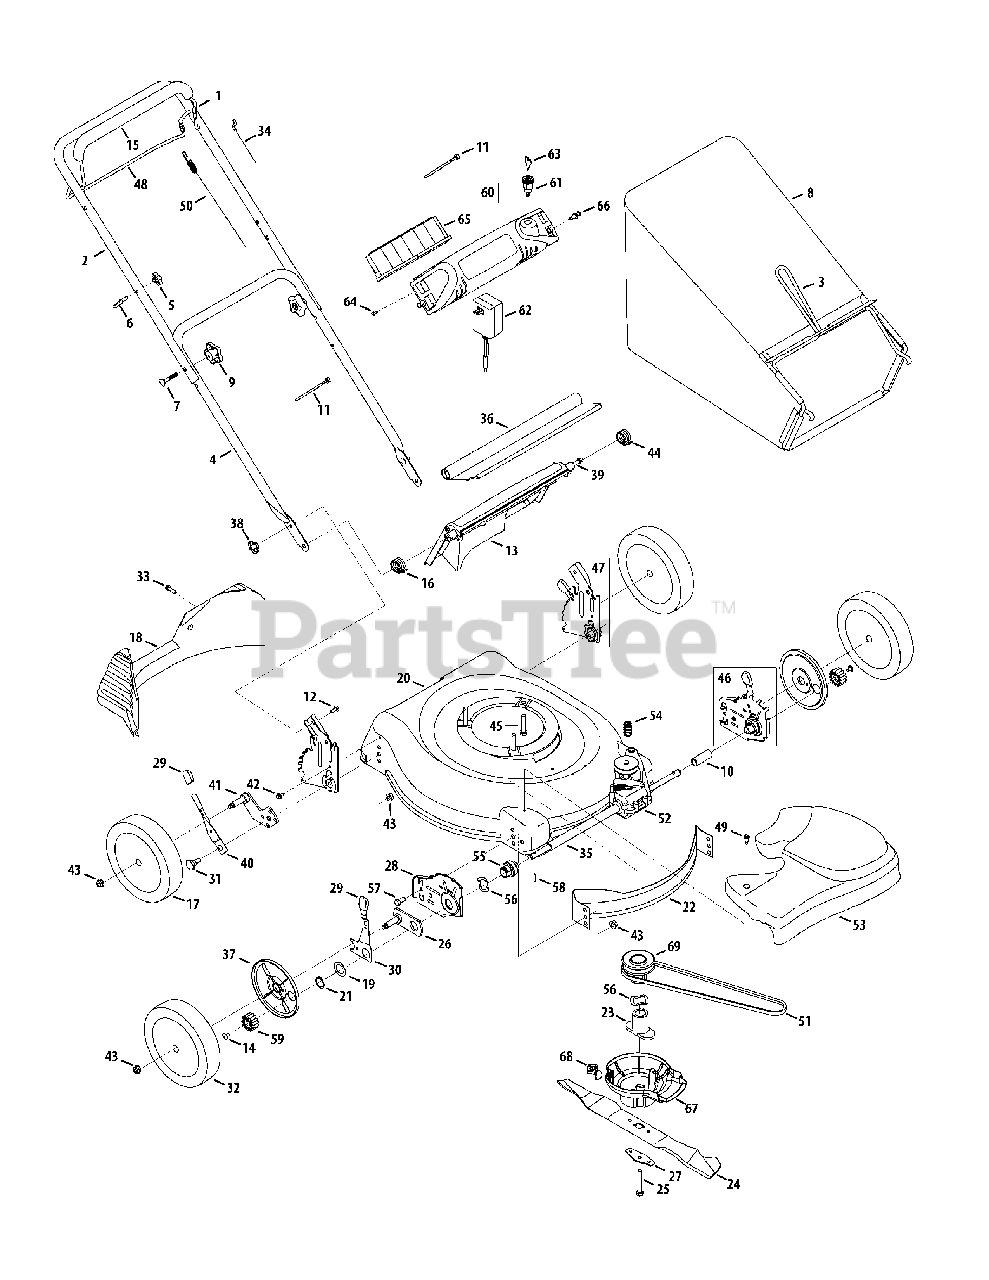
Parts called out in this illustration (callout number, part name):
6	Rope Guide
7	Carriage Bolt ,5/16-18 x 2
8	Grass Bag Assembly
9	Hand Knob
10	Sleeve Spacer - LH
11	Cable Tie
12	Carriage Bolt ,1/4-20
13	Rear Discharge Door
14	Screw 1/4-20
15	Bail Cover
16	Torsion Spring - RH
17	Rear Wheel, 8" x 2.125"
18	Rear Baffle
19	Washer, 1.5" OD
21	Snap Ring
22	Front Baffle
23	Blade Adapter
23	One Piece Blade Adapter
24	21" Mulch Blade
25	Hex Bolt , 3/8-24 x 2.5
26	Pivot Plate Assembly
27	Blade Bell Support
28	Height Adjustment Plate - RH
28	Height Adjustment Plate - LH
29	Adjustment Lever Knob
30	Front Lever - RH
30	Front Lever - LH
31	Shoulder Screw
32	Front Wheel, 8" x 2.125"
33	Screw, 1/4-15 x 1.000
34	Control Cable - 40.75"
35	Sleeve Spacer - RH
36	Trailshield
37	Wheel Dust Cap
38	Wing Nut, 1/4-20
39	Rear Door Pivot Rod
40	Spring Lever
41	Pivot Arm Assembly - RH
41	Pivot Arm Assembly - LH
43	Flange Lock Nut, 3/8-16
44	Torsion Spring - LH
45	TT Sems Screw, 3/8-16 x 1.00
46	Ht. Adjustment Assy. Front - LH
46	Ht. Adjustment Assy. Front - RH
47	Rear Handle Bracket Assy. - LH
47	Rear Handle Bracket Assy. - RH
48	Drive Control
49	Shoulder Screw
50	Drive Cable
51	V-Belt
52	Transmission Assembly
53	Front Drive Cover
54	Belt Tension Spring
55	Bearing Assembly
56	Wave Washer
57	Hex Screw
58	Dowel Pin
59	Gear, 14T - RH
59	Gear, 14T - LH
60	Electric Start Harness Assembly
61	Key Switch
62	Battery Charger 12V
63	Key
64	Screw, #10-16 x .75
65	12 Volt Battery
66	Plastic Rivet
67	Engine Baffle
68	Engine Baffle Bracket
69	Drive Pulley Assembly
